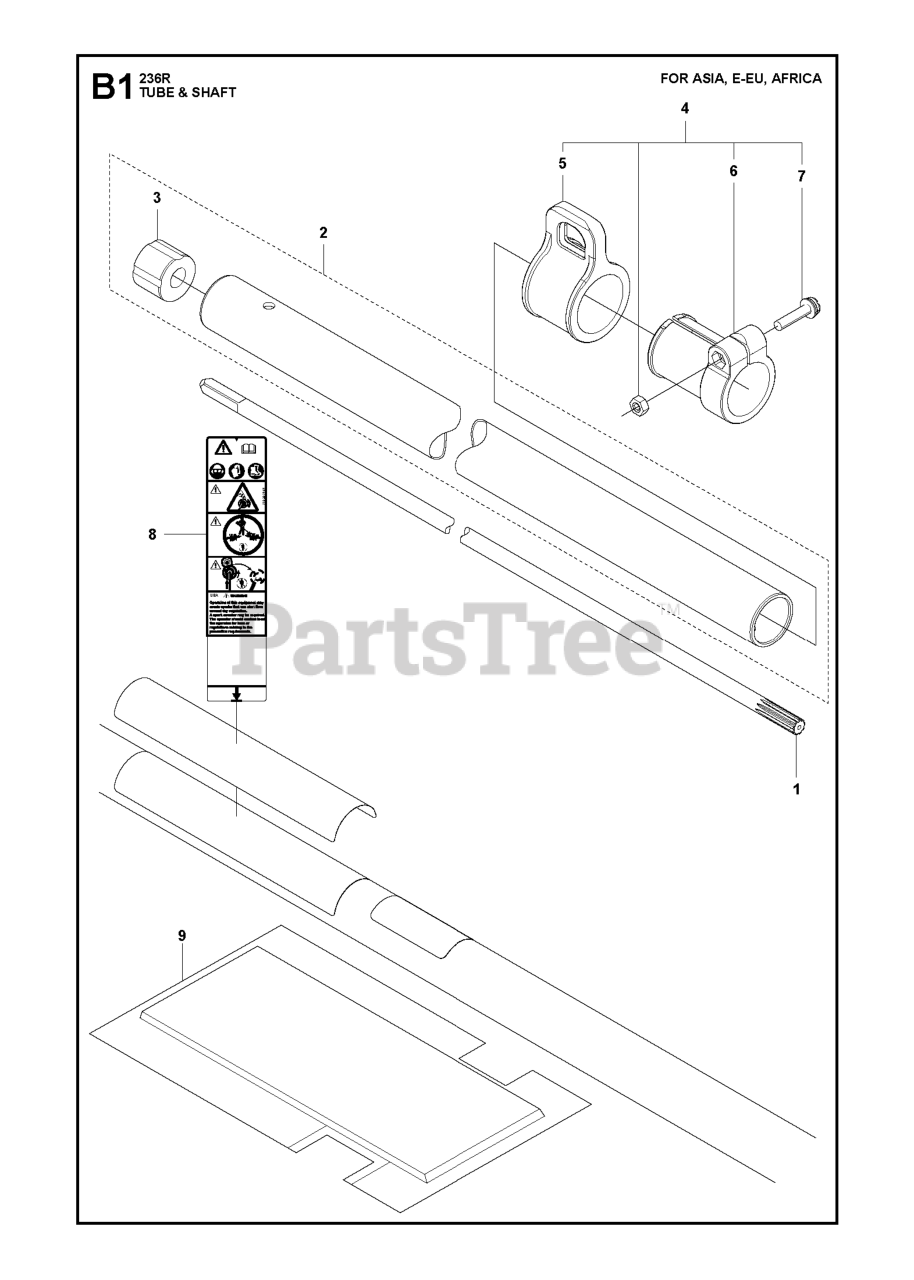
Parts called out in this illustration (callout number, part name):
1	DRIVE SHAFT
2	PIPE COMP.
8	LABEL WARNING TRIMMERS AND BRU
9	PROTECTOR (RPLS 405017110)
